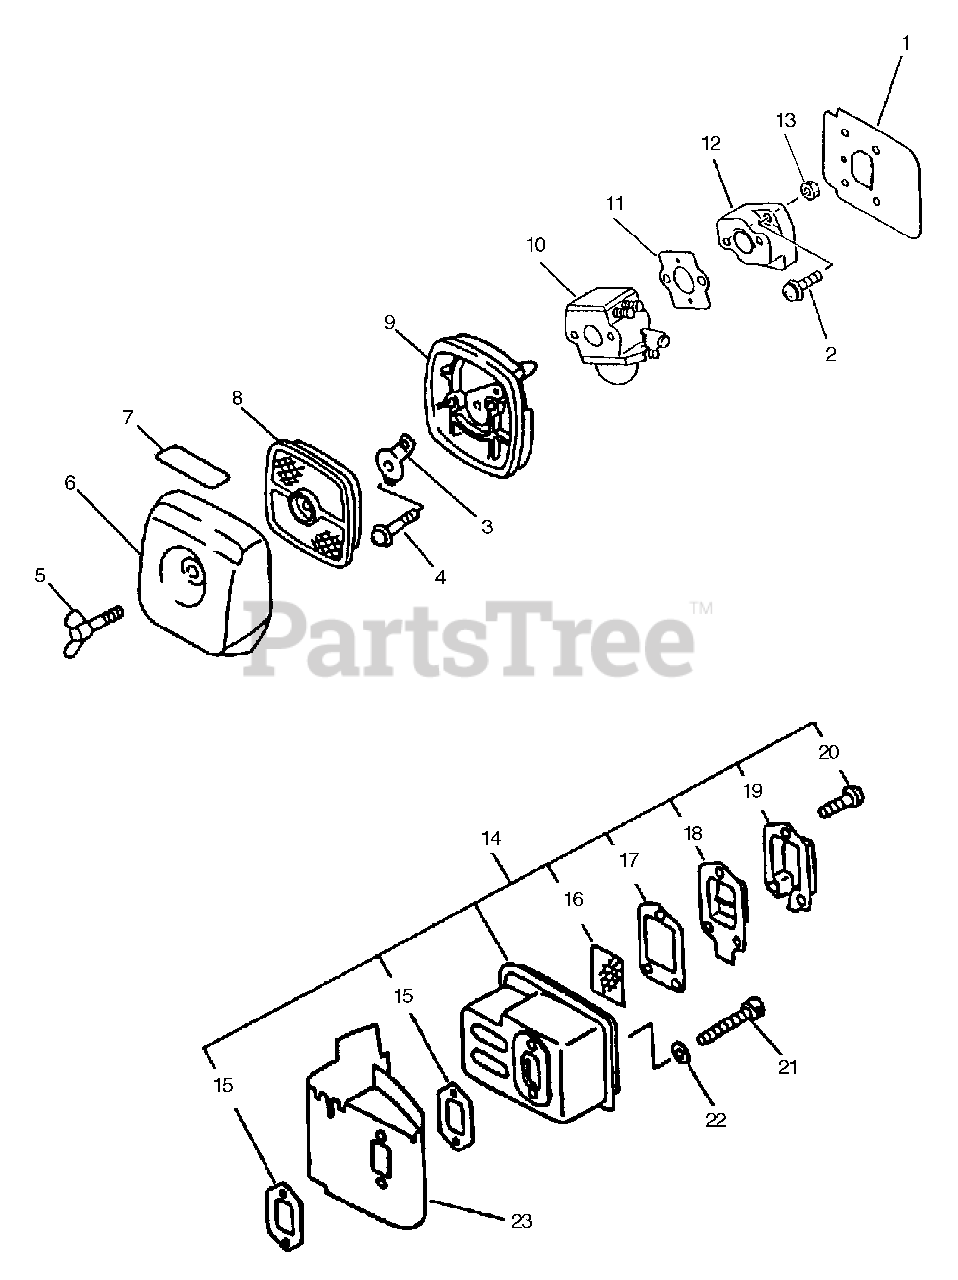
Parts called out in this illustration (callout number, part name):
1	SHIELD, INTAKE
2	SCREW - 5X20
3	PLATE, PREVENT
4	SCREW - 5X65
5	THUMBSCREW
6	COVER, AIR FILTER - GRAY
7	LABEL - CHOKE
8	FILTER, AIR
8	FILTER, AIR - SINGLE LAYER
9	AIR FILTER CASE ASSY
10	CARBURETOR C1U-K51
11	GASKET, INTAKE
12	INSULATOR, INTAKE
14	MUFFLER ASSY
15	GASKET, EXHAUST
16	SCREEN, SPARK ARRESTOR
17	GASKET, EXHAUST
18	GASKET, EXHAUST - INNER
19	GUIDE, EXHAUST - OUTER
20	SCREW - 4X10
21	SCREW - 5X50
22	WASHER - 5
23	SHIELD, EXHAUST
